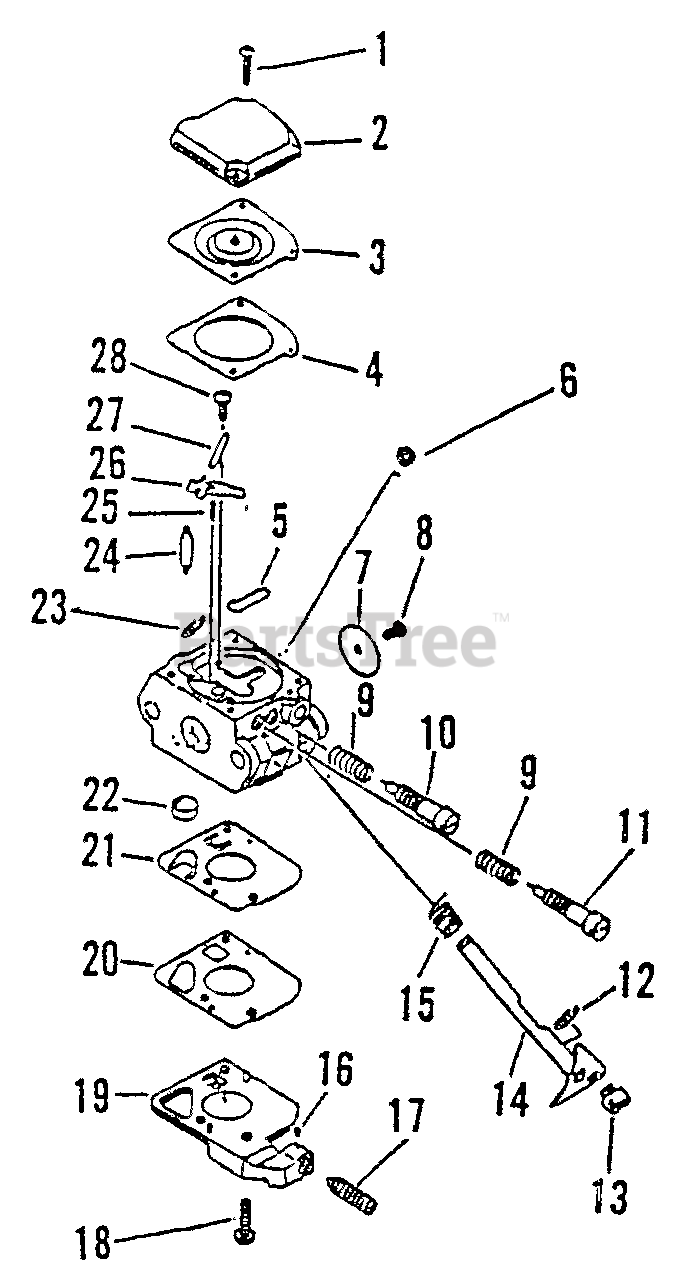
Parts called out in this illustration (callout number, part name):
1	CARBURETOR - C1U-K9
2	COVER, DIAPHRAGM
3	DIAPHRAGM
4	GASKET, METERING
5	PLUG, WELCH
6	NOZZLE, CHECK VALVE
7	VALVE, THROTTLE
9	SPRING, NEEDLE
10	NEEDLE, HIGH SPEED
11	NEEDLE, LOW SPEED
14	SHAFT, THROTTLE
15	SPRING, THROTTLE RETURN
16	PIECE, FRICTION
17	SCREW, IDLE ADJUST
19	COVER, PUMP
24	VALVE, NEEDLE
25	SPRING
26	LEVER, METERING
27	PIN
